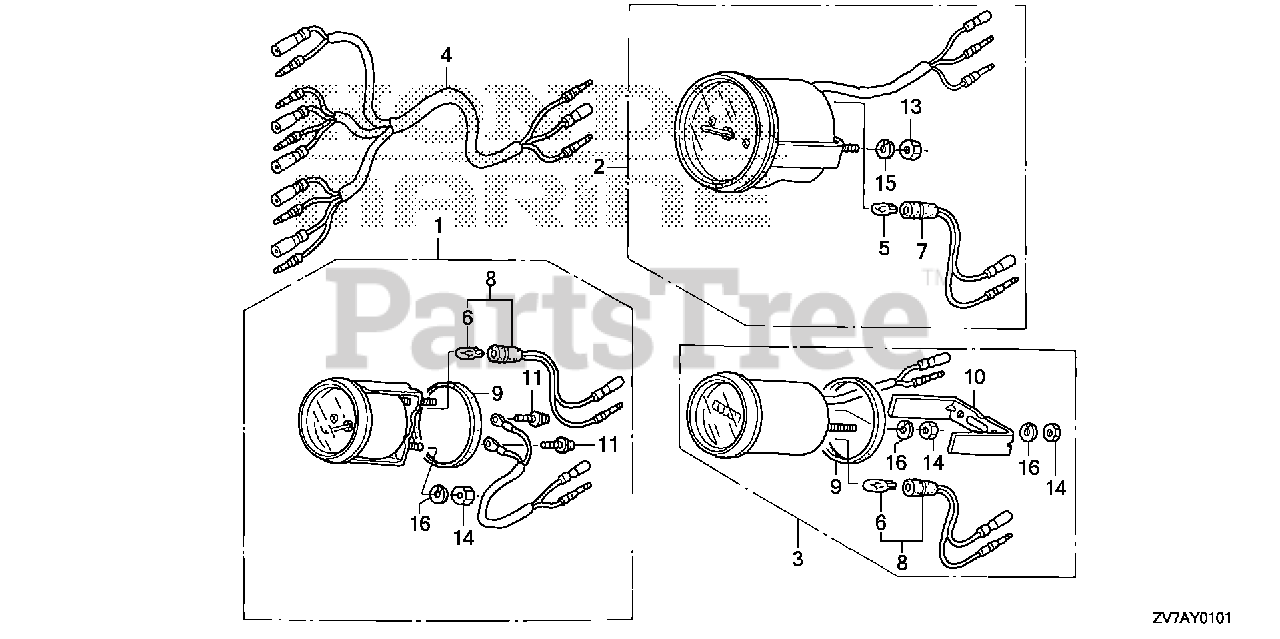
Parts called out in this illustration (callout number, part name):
1	METER KIT, VOLT
1	METER KIT, VOLT (B)
2	METER KIT, TACHO
2	METER KIT, TACHO (B)
3	METER KIT, HOUR (NA USE ALT:39700-ZW5-000ZA)
3	METER KIT, HOUR (B) (NA USE ALT:39700-ZW5-000ZA)
4	HARNESS ASSY., METER (B)
5	BULB, WEDGE BASE (T10) (12V 1.7W) (STANLEY)
6	BULB, WEDGE BASE (12V 1.7W)
7	SOCKET
8	SOCKET
9	GASKET
10	BRACKET
11	SCREW-WASHER (3X22)
13	NUT, HEX. (5MM)
14	NUT, HEX. (4MM)
15	WASHER, SPRING (5MM)
16	WASHER, SPRING (4MM)
